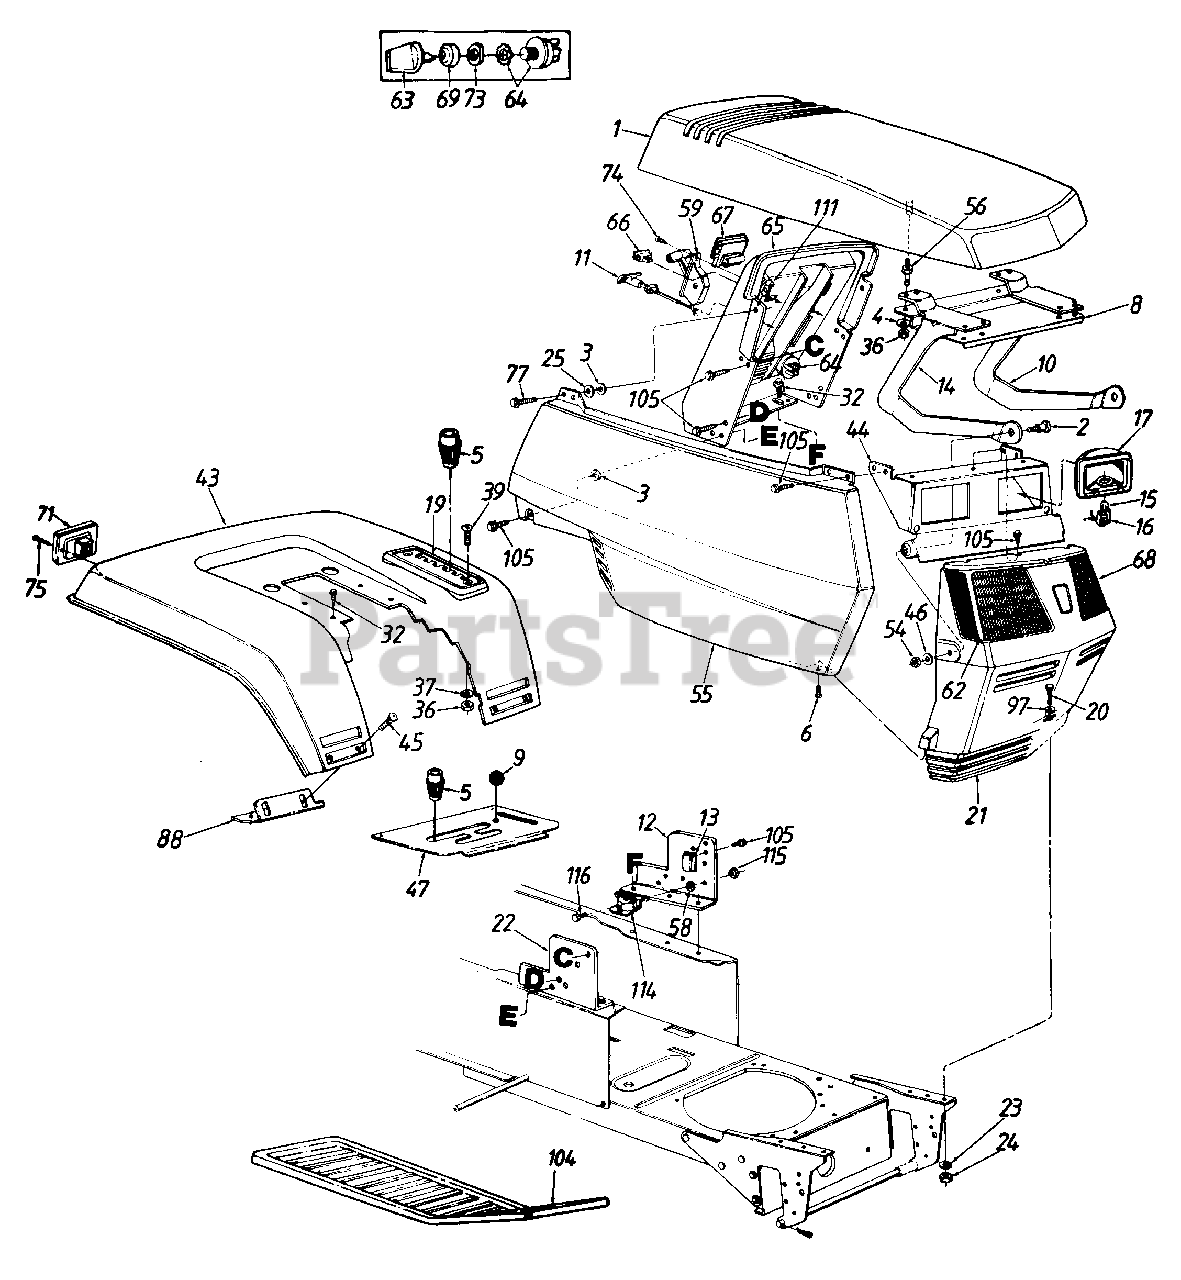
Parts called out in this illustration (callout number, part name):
3	Bolt Retainer 1/4" I.D.
4	Bell-Wash. .265" I.D. x .75" O.D.
5	Shift Knob
6	Truss Mach. B-Tap Scr. #10 x 5n Lg.
8	Hood Reinforcement
9	Ball Knob-Brake
10	Hood Hinge-L.H.
11	Choke Control
12	Dash Support Brkt.-L.H.
13	Circuit Breaker
14	Hood Hinge-R.H.
15	Lamp
16	Twist Lock-Lamp Socket
17	Headlight Housing
19	Speed Control Index Brkt.
20	Hex Bolt 5/16-18 x .75" Lg.
23	L-Wash. 5/16" I.D.*
24	Hex Nut 5/16-18 Thd.
25	Fl-Wash. 1/4" I.D. x .93" O.D.
32	Hex Wash. Hd. AB-Tap Scr. 5/16 x .75" Lg.
36	Hex Nut 1/4-20 Thd.
37	L-Wash. 1/4n I.D.
39	Truss Mach. Scr. 1/4-20 x .62n Lg.
46	Fl-Wash. .328" I.D. x .68" O.D.
47	Transmission Panel
54	Hex Cent. L-Nut 5/16-18 Thd.
55	Side Cover-R.H.
56	Double Ended Stud 1/4-20 Thd.
58	Ext. L-Wash. 114" I.D.
59	Throttle Control Box Ass'y.
62	Lens-R.H.
63	Ignition Key
64	Ignition Switch
65	Dash Panel
66	Light Switch
67	Ammeter
68	Lens-L.H.
69	Ignition Switch Cap
71	Taillight Ass'y.
73	Ignition Switch Nut
74	Truss Mach. AB-Tap Scr. #10 x .5" Lg.
75	Truss Hd. AB-Tap Scr. #6 x .62" Lg.
77	Hex Wash. Hd. Tap Scr. 1/4 x .75" Lg.
104	Foot Pad
105	Hex Tap Scr. 1/4-20 x .5" Lg.
111	Speed Nut 1/4-20 Thd.
114	Solenoid
115	Hex Sems Nut 1/4-20 Thd.
116	Hex Bolt 1/4-20 x .5" Lg.
